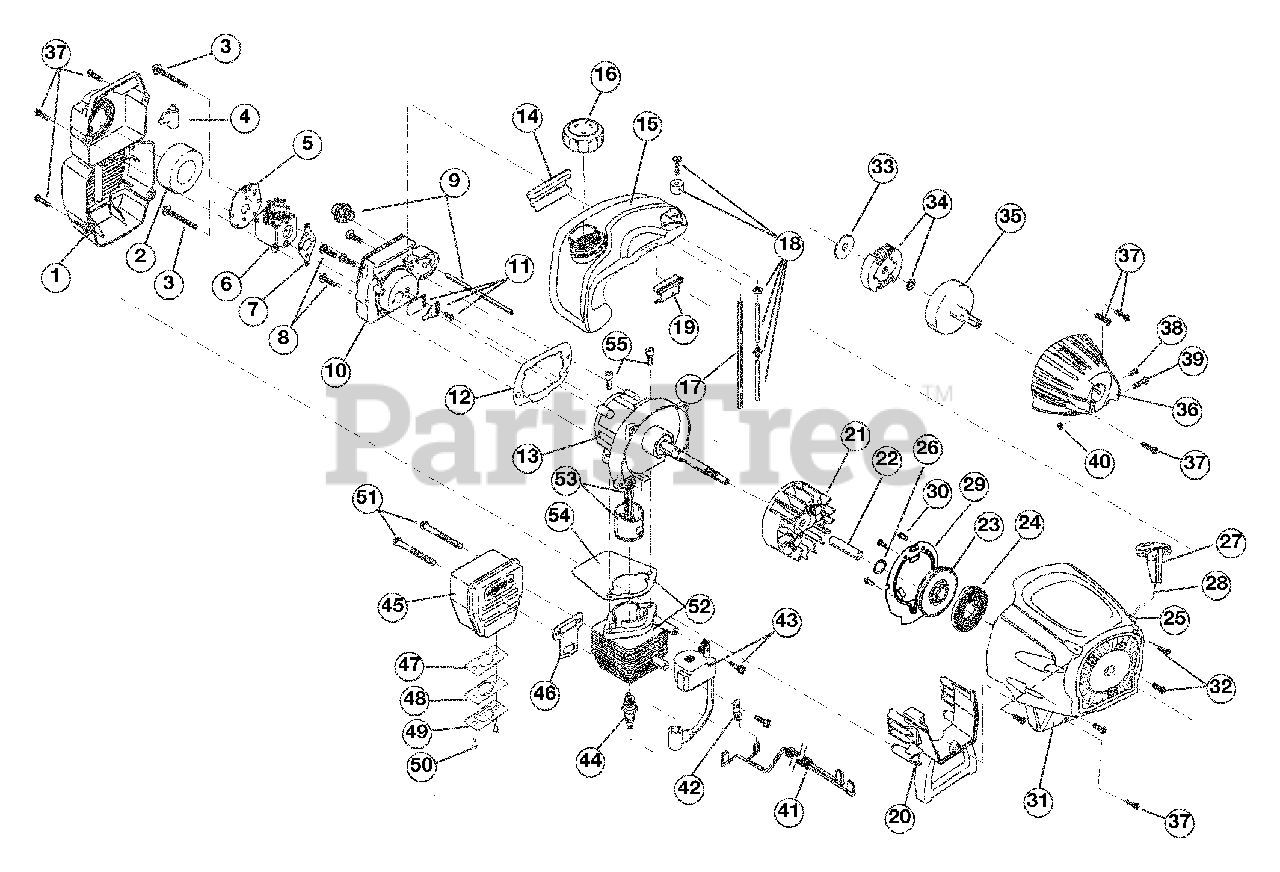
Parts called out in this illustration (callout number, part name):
1	Air Cleaner Cover Assembly
2	Air Cleaner Filter
3	Carburetor Mounting Screw Assembly
4	Choke Extension
5	Choke Plate
6	Carburetor Assembly
7	Carburetor Gasket
8	Carb Mount Screw
9	Primer & Hose Assembly
10	Carb Mount Assembly
11	Reed Assembly
12	Carburetor Mount Gasket
13	Crankcase Service Assembly
14	Rear Mounting Pad
15	Fuel Tank Assembly
16	Fuel Cap Assembly
17	Fuel Return Line
18	Fuel Line Assembly
19	Front Mounting Pad
20	Shroud Extension & Stand
21	Flywheel Assembly
23	Recoil Pulley Assembly
24	Recoil Spring
25	Rope Guide
26	Pulley Retainer
27	Pull Handle
29	Pressure Plate Assembly
30	Plate Screw
31	Starter Housing Assembly
32	Housing Screw
33	Clutch Washer
34	Clutch Rotor Assembly
35	Clutch Drum Assembly
36	Clutch Cover Assembly
37	Cover Screw
38	Anti-Rotation Screw
39	Clamping Screw
40	Clamping Nut
41	Wire Leads and Sleeve
42	Ground Tab
43	Module Assembly
45	Muffler Assembly
46	Exhaust Gasket
47	Spark Arrestor Screen
48	Exhaust Hood Diverter
49	Exhaust Hood
50	Screws
51	Muffler Mounting Bolts
52	Cylinder Assembly
53	Piston and Rod Assembly
54	Cylinder Gasket
55	Cylinder Bolt
